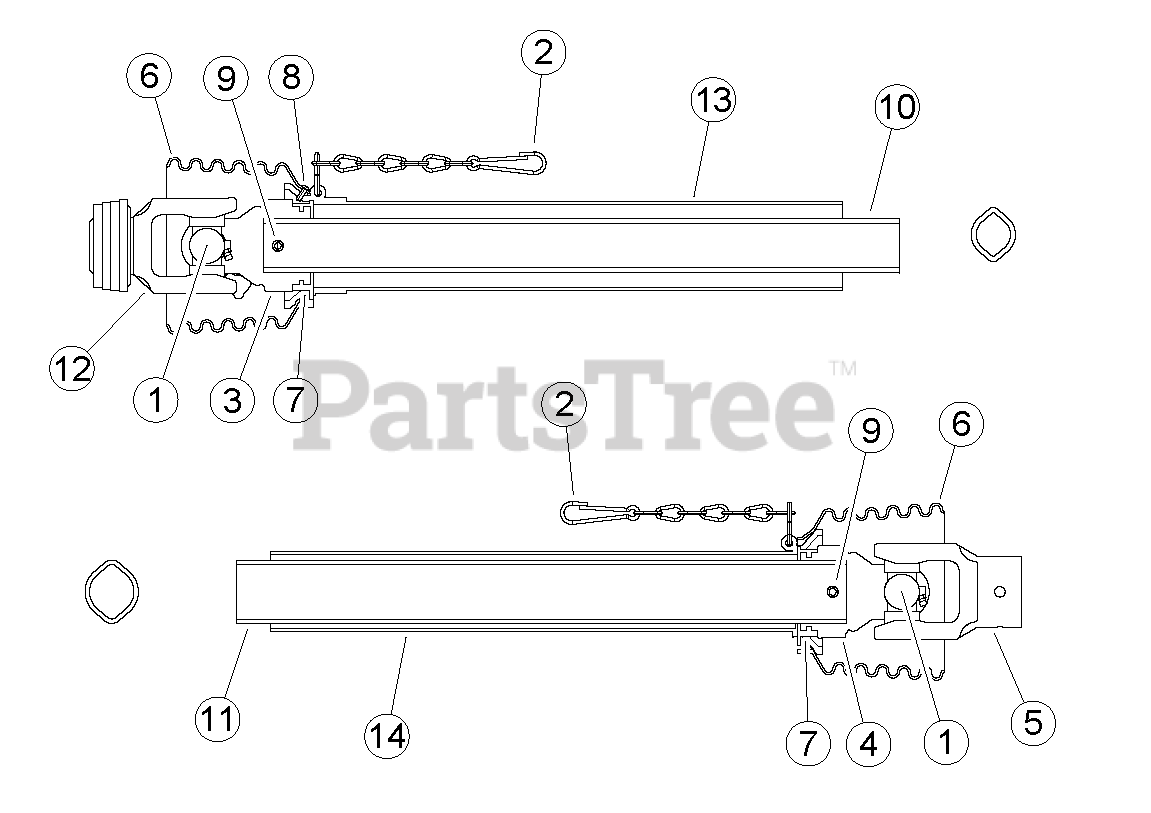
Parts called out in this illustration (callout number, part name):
1	KIT, CROSS & BEARING W-2400
2	CHAIN, SAFETY
3	YOKE, INBOARD 1B
4	YOKE, INBOARD 2A
5	YOKE, 1-1/2 RND
6	CONE, 6 RIB SAFETY
7	RING, SC25 BEARING
8	SCREW, WS365305
9	PIN, M10 X 80 SPRING
10	PROFILE, INNER 1B
11	PROFILE, OUTER 2A
12	YOKE, 1-3/8-6 SPLINGE ASGE
13	GUARD, TUBE OUTER
14	GUARD, TUBE INNER
